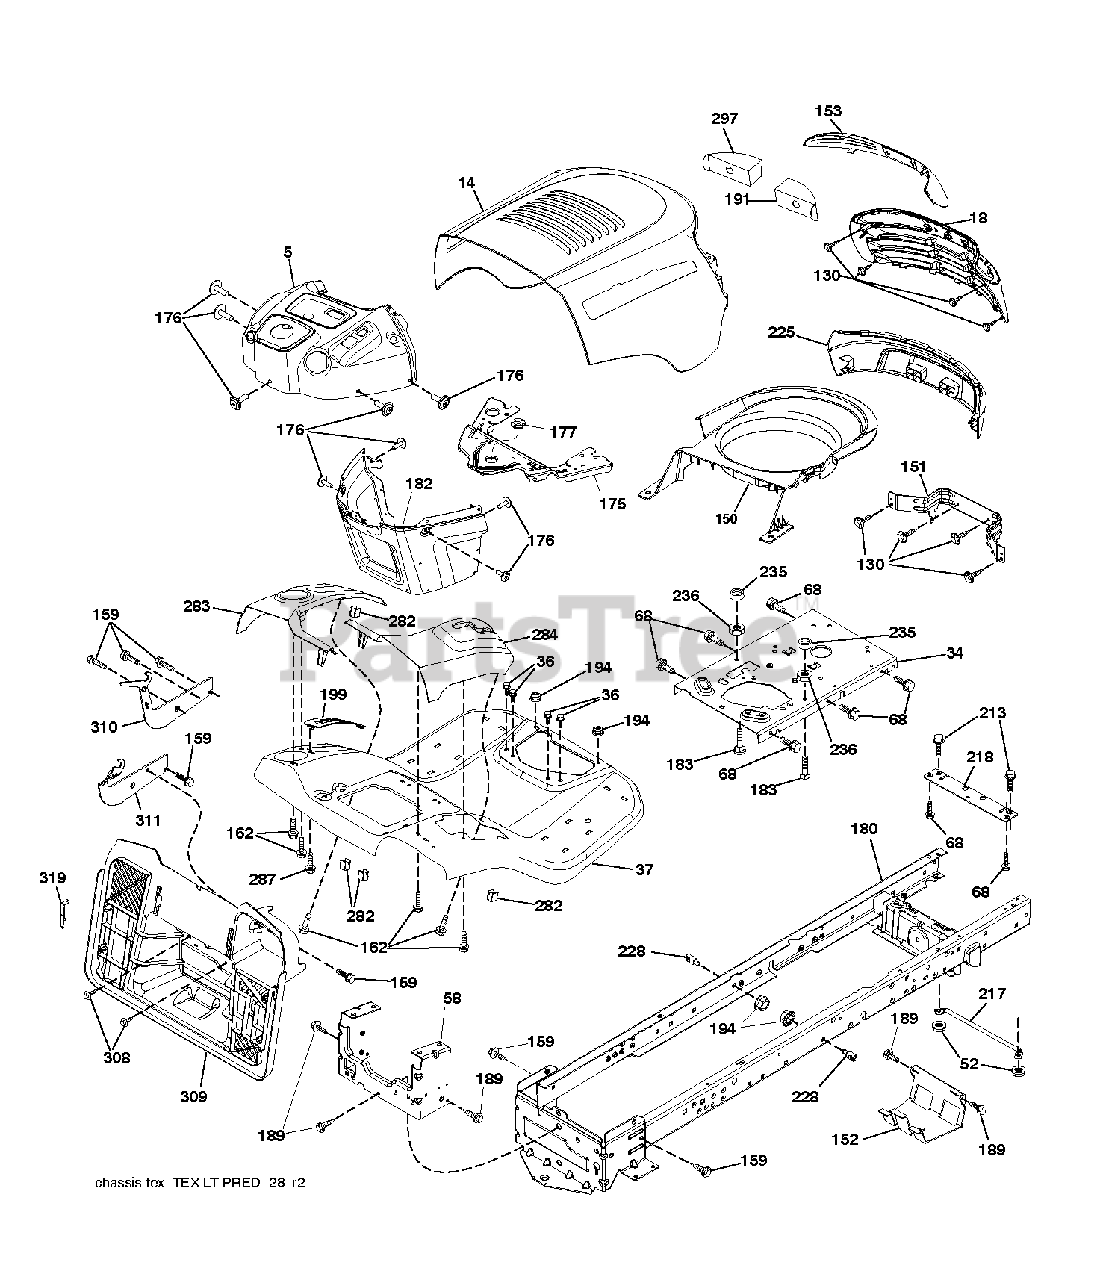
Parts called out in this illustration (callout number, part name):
5	DASH.PRED.LT.CC.ICY.N/SRV.BLK
14	HOOD.PREDATR.LT.U-FRM.TPVNT428
18	GRILLE.SVC.BASE.PREDATOR.LT428
34	PLATE.ENGINE.WELDED.CHASSIS
36	SCREW 5/16"
37	FENDER.TEX.SRD.CRD.BASE
52	LOCKNUT
58	DRAWBAR UPPER 2PC SMALL FENDER
130	SCREW.#10 X 0.750.BOS THREAD
151	BRACKET.PIVOT.ALPHA.LT
152	SHIELD BROWNING
153	LENS.PREDATOR.LT.
159	SCREW, 3/8-16X3/4
162	SCREW.HI-LO.CONSOLE
176	SCREW.#10-24X5/8.RN.QU
177	BUSHING STEERING
180	CHASSIS.WLDMNT.14GA.2PC.18".TI
182	DASH.LWER.PREDATOR/HUSQ.LT
183	BOLT.5/16-18X1-1/4 FULL THD
189	SCREW
191	INSERT.REFLECT.PREDATOR.LT.RH
194	NUT LOCK HEX FLANGE 5/16-18
213	BOLT
217	ROD.PIVOT.HOOD
218	X-PIECE.HOOD.STOP.NON/
228	STUD.FASTNER.W/ANTI-ROTATE
235	SPACER FENDER
236	NUT.CENTERLOCK.5/16-
282	CLIP.RETAINER.CONSOLE.LT.HUSQ
283	CONSOLE.DECKLIFT.LH.SRD.TEXCRD
297	REFLECTOR.INSERT.PRED.LH.LT
308	BOLT, 5/16-18 X 1 3/4
309	BACKPLATE.BAGGER.V2.SRD
319	BRACKET.ACTUATOR.BAGGER.SRD
